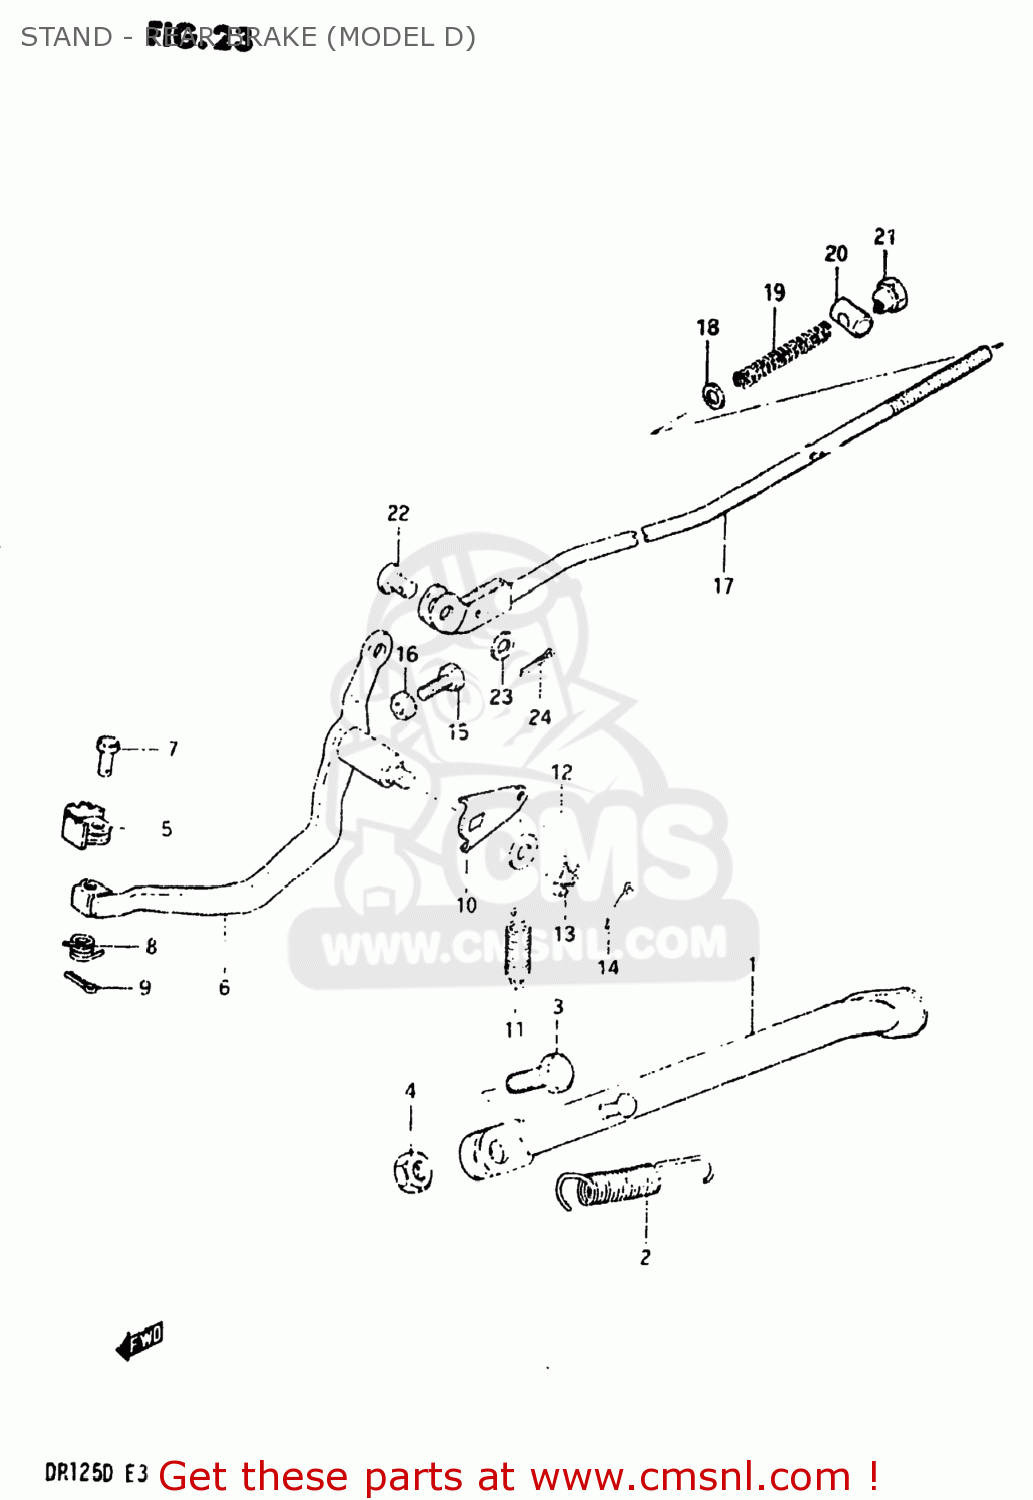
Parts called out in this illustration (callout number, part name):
1	STAND,SIDE
2	SPRING
3	BOLT(10X30)
4	NUT
5	PEDAL,BRAKE
6	ARM,BRAKE PEDAL
7	PIN
8	SPRING
9	PIN
10	ARM,BRAKE RETURN SPRING
11	SPRING
12	WASHER
13	NUT 8MM
14	PIN 20X20
15	BOLT(6X23)
16	NUT
17	ROD ASSEMBLY,REAR BRAKE
18	WASHER
19	SPRING
20	PIN
21	NUT (6MM)
22	PIN
23	WASHER
24	PIN 20X20
